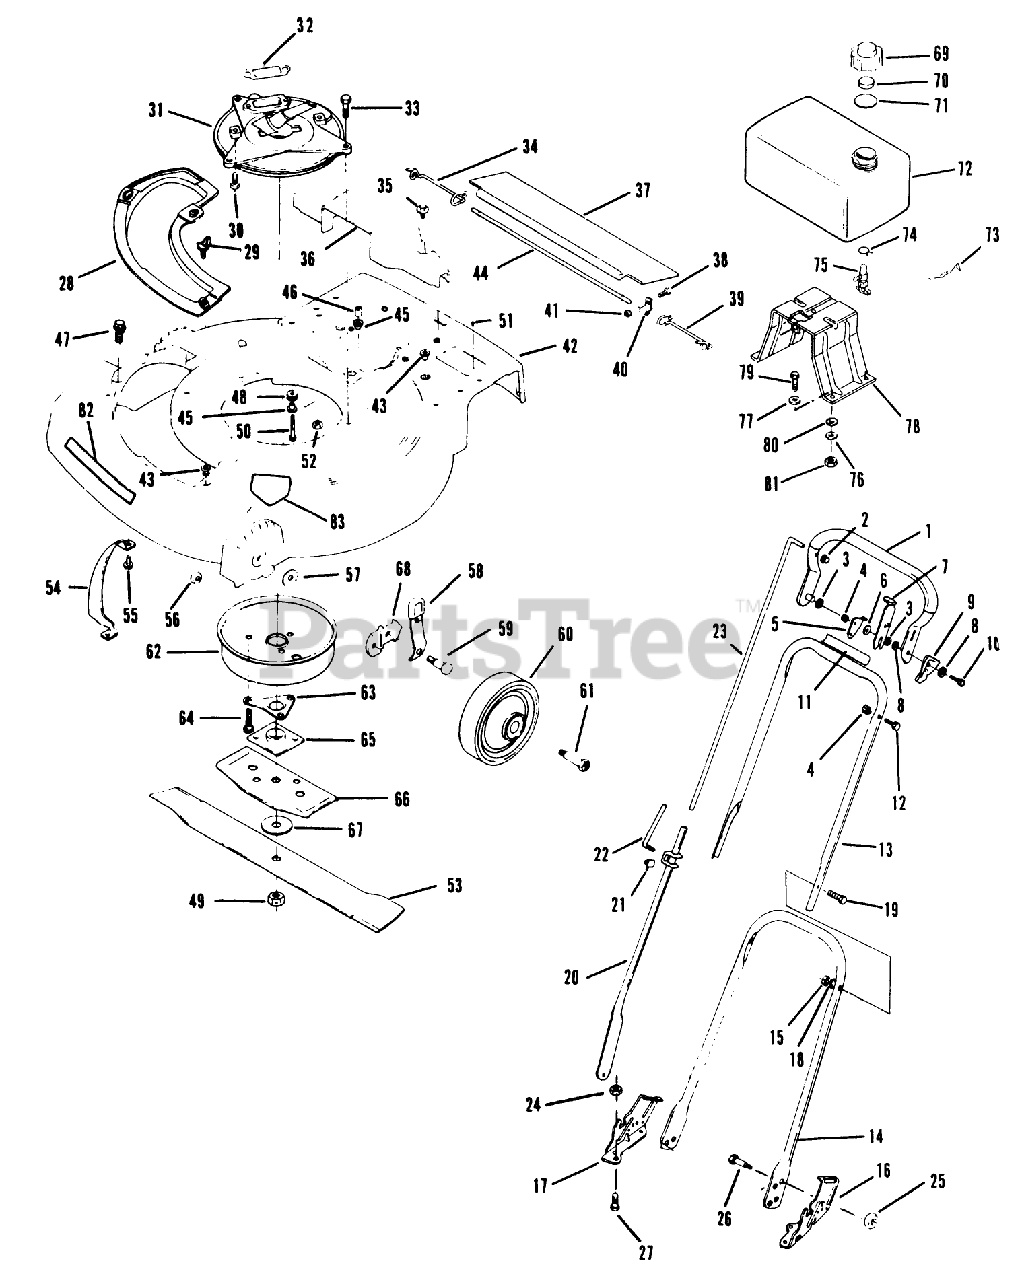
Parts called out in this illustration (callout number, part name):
3	WASHER M
4	LOCKNUT E
5	HANDLE STOP
10	BOLT PIONEER
12	SCREW-HANDLE STOP
15	LOCKNUT E
18	WASHER-CURVED
23	ROD CONTROL
24	NUT-LOCK F
25	NUT-JAM, LOCKING
29	WING SCREW LAWRE
30	SCREW V
34	SPRING;TRAILING SHIELD RH
35	SCREW SEMS TRM HEX HD
39	SPRIG T/SHLD ASOC
40	CLAMP ROD KMC
41	LOCKNUT E
44	ROD 21" ADVANCE
45	SPACER ECK PRES
48	GROMMET
49	NUT-BLADE
52	NUT-LOCK F
54	BAR-TOE
56	LOCKNUT
60	WHEEL & TIRE ASSY
61	BOLT-SHOULDER
63	SUPPORT F
65	PLATE AND COLLAR ASM
70	BAFFLE - FOAM SM
71	GASKET S
74	CLAMP - HOSE S
75	VALVE&SCREEN SM
79	BOLT PIONEER
81	LOCKNUT E
